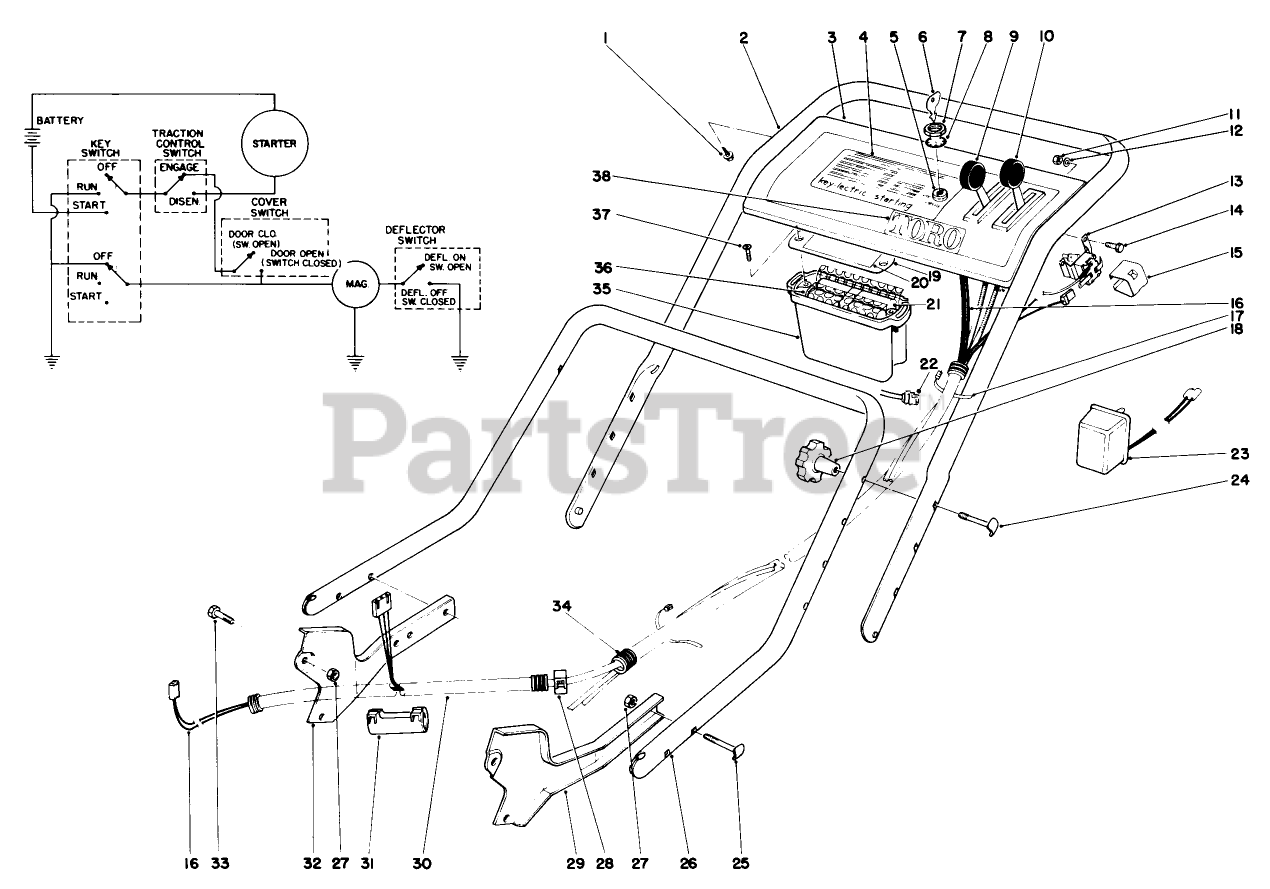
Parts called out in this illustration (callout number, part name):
1	SCREW-HWHTF
3	Control Plate
4	Decal-Control Plate
5	SWITCH-STARTER
7	WASHER-LOCK
8	NUT-HH
11	NUT-HEX
12	WASHER-FLAT
13	CONTROL SWITCH
14	DISC PREC HUSKY
17	TIE-CABLE
25	Handle Screw
26	Lower Handle
28	RING FITTING
29	Latch Handle L.H.
33	SCREW-HH
38	TORO LOGO DECAL
